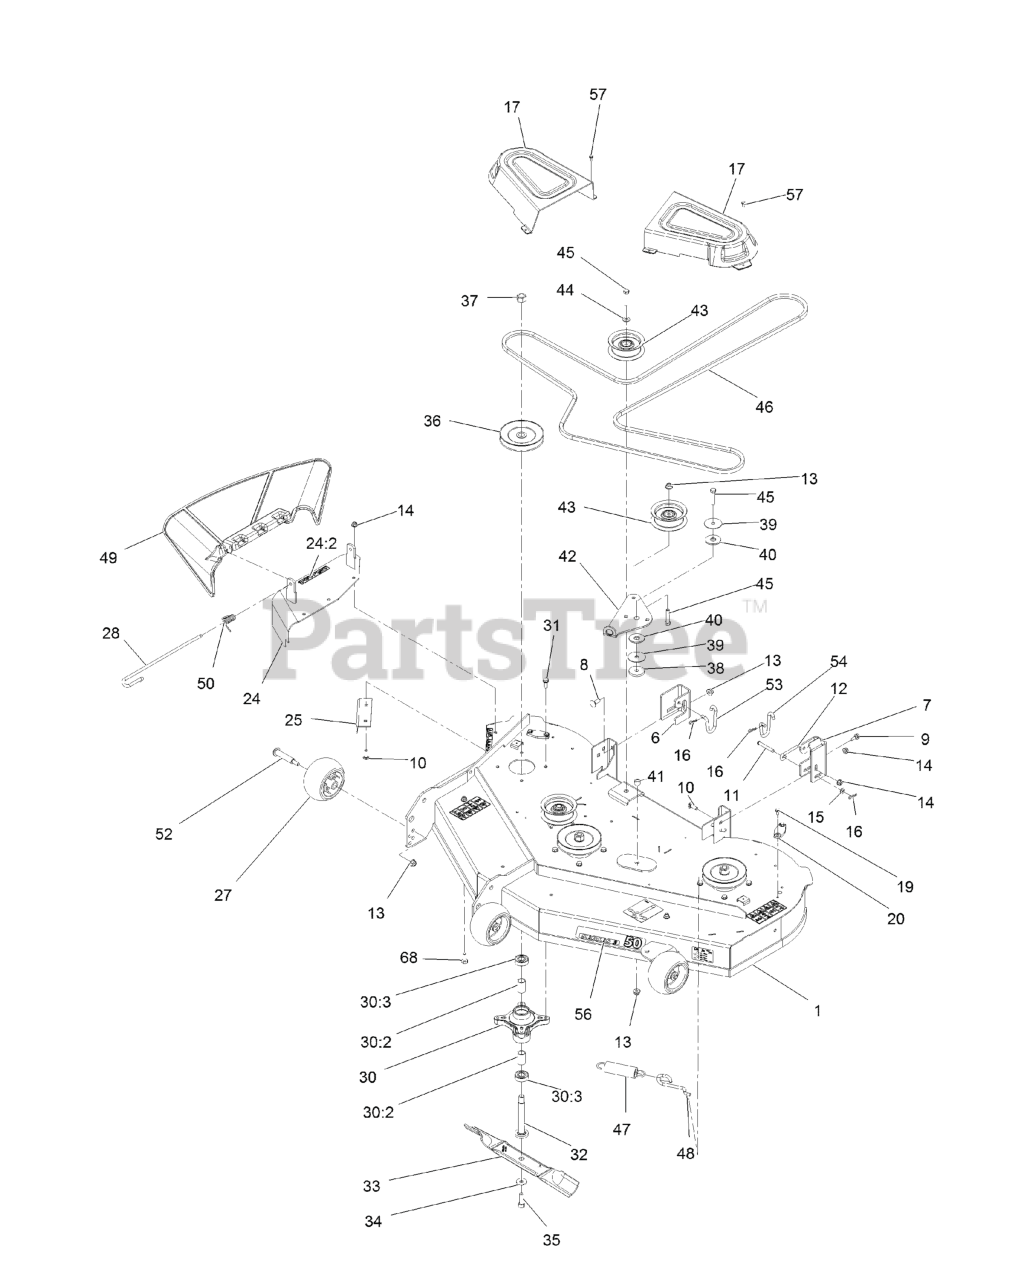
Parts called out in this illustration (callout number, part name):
1	DECK-50 W/DECALS
6	BRACKET-HANGER, RH
7	BRACKET-HANGER, LH
8	BOLT-CARR
9	SCREW-SHOULDER,HWH
10	SCREW-CARR
11	PIN-CLEVIS
12	ROD-LEVEL, DECK
13	NUT-HF, NI
14	NUT-HF, NI
15	WASHER-PLAIN
16	PIN-COTTER
17	COVER-BELT
19	SCREW-HWH
20	COVER-WASHOUT PORT
24	COVER ASM W/DECAL
24:2	DECAL-DANGER
25	BAFFLE-CUTOFF
27	ROLLER-SCALP, ANTI
28	PIN-CHUTE
30	SPINDLE ASM
30:3	BEARING-BALL
31	SCREW-TAPTITE
32	SHAFT-SPINDLE
33	BLADE-HI LIFT
34	WASHER-BELLEVILLE
35	SCREW-HH
37	NUT-HEX
38	WASHER-PLAIN
40	WASHER-FRICTION, COMPOSIT
42	ARM-IDLER
43	PULLEY-IDLER, FLAT
44	WASHER-FLAT
45	SCREW-HH
46	V-BELT
47	SPRING-EXTENSION
48	HOOK-RETURN, SPRING
49	DEFLECTOR-DISCHARGE
50	SPRING-TORSION
52	BOLT-SHOULDER
53	LINK-RETENTION, DECK (RH)
54	LINK-RETENTION, DECK (LH)
56	DECAL-SERIES 2 - 50
57	SCREW-TAPTITE
68	SCREW-HH
